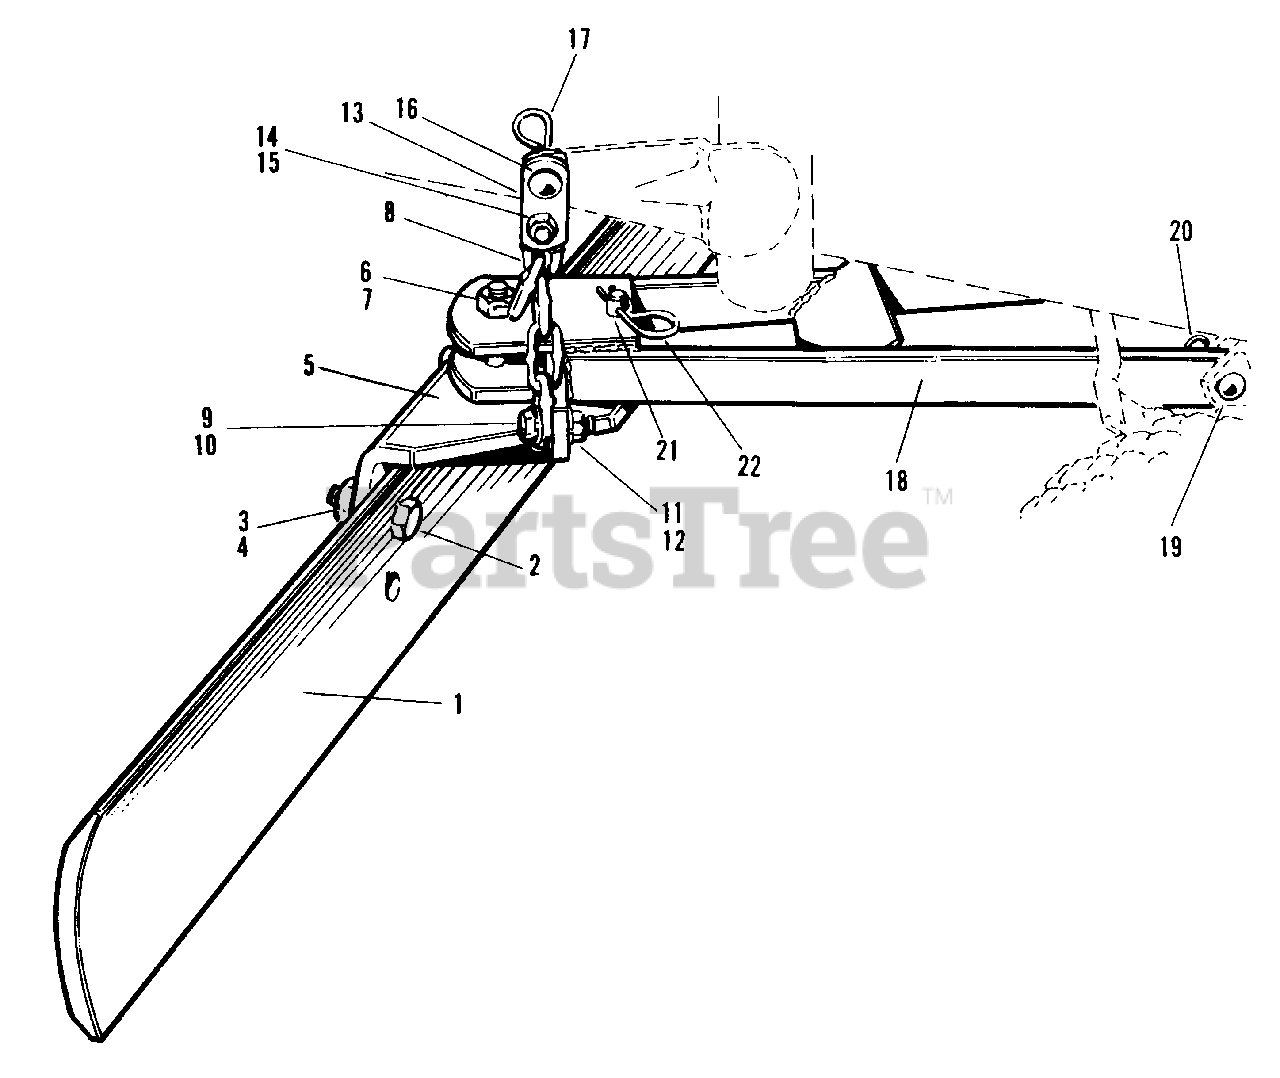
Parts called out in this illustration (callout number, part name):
1	BLADE, Grader, 40"
2	CAPSCREW, Hex, 5/8-11 x 2
3	LOCKWASHER, 5/8
4	NUT, 5/8-11
6	CAPSCREW, 5/8-11 x 3
7	LOCKNUT, 5/8-11
8	CHAIN
9	CAPSCREW, Hex, 3/8-16 x 1-1/4
10	WASHER, Flat, 3/8
11	LOCKWASHER, 3/8
12	NUT, 3/8-16
14	CAPSCREW, 3/8-16 x 1
15	LOCKNUT, 3/8-16
17	CLIP, Hairpin
18	BAR ASSY., Pull
20	CLIP, Hairpin
22	CLIP, Hair Pin
